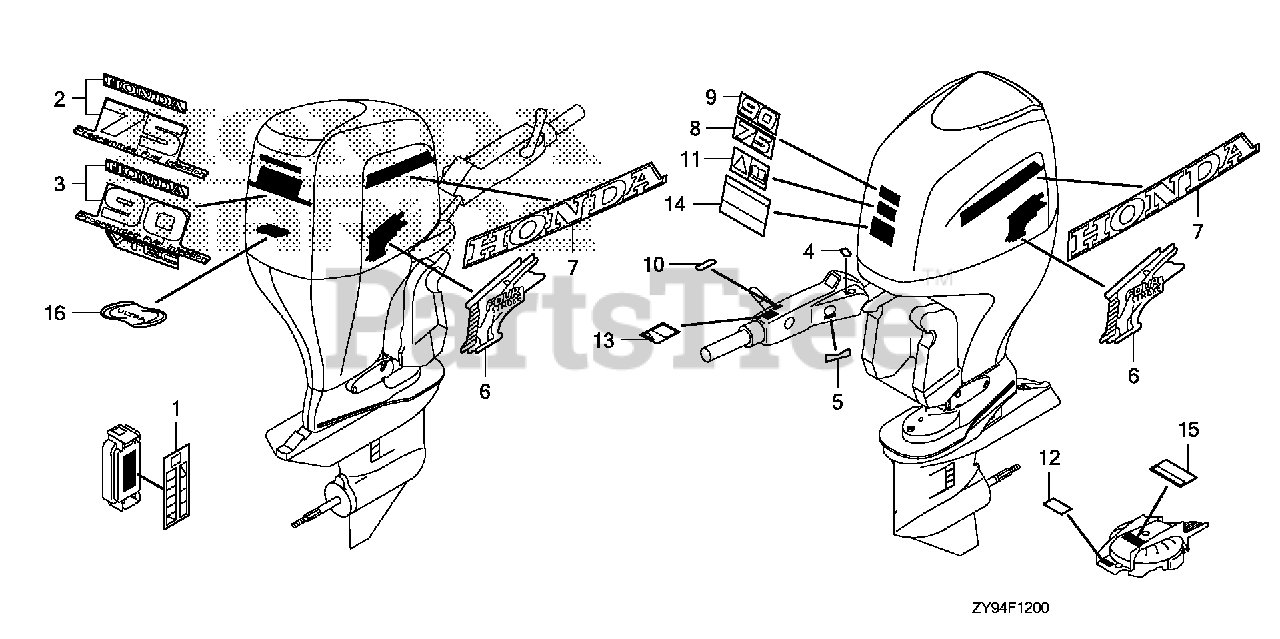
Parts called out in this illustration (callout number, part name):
1	LABEL, FUSE
2	MARK, RR. (75)
4	MARK, EMERGENCY SWITCH INDICATION
4	MARK, EMERGENCY SWITCH INDICATION (EU)
5	MARK, STARTER (ENGLISH)
6	MARK, SIDE
7	MARK, SIDE STRIPE
8	MARK, FR. EMBLEM (75)
10	MARK, CHANGE (JAPANESE/ENGLISH)
12	LABEL, CAUTION OIL (ENGLISH)
13	MARK, THROTTLE (ENGLISH)
14	LABEL, CAUTION OPERATOR (ENGLISH)
15	MARK, EMERGENCY START (ENGLISH)
